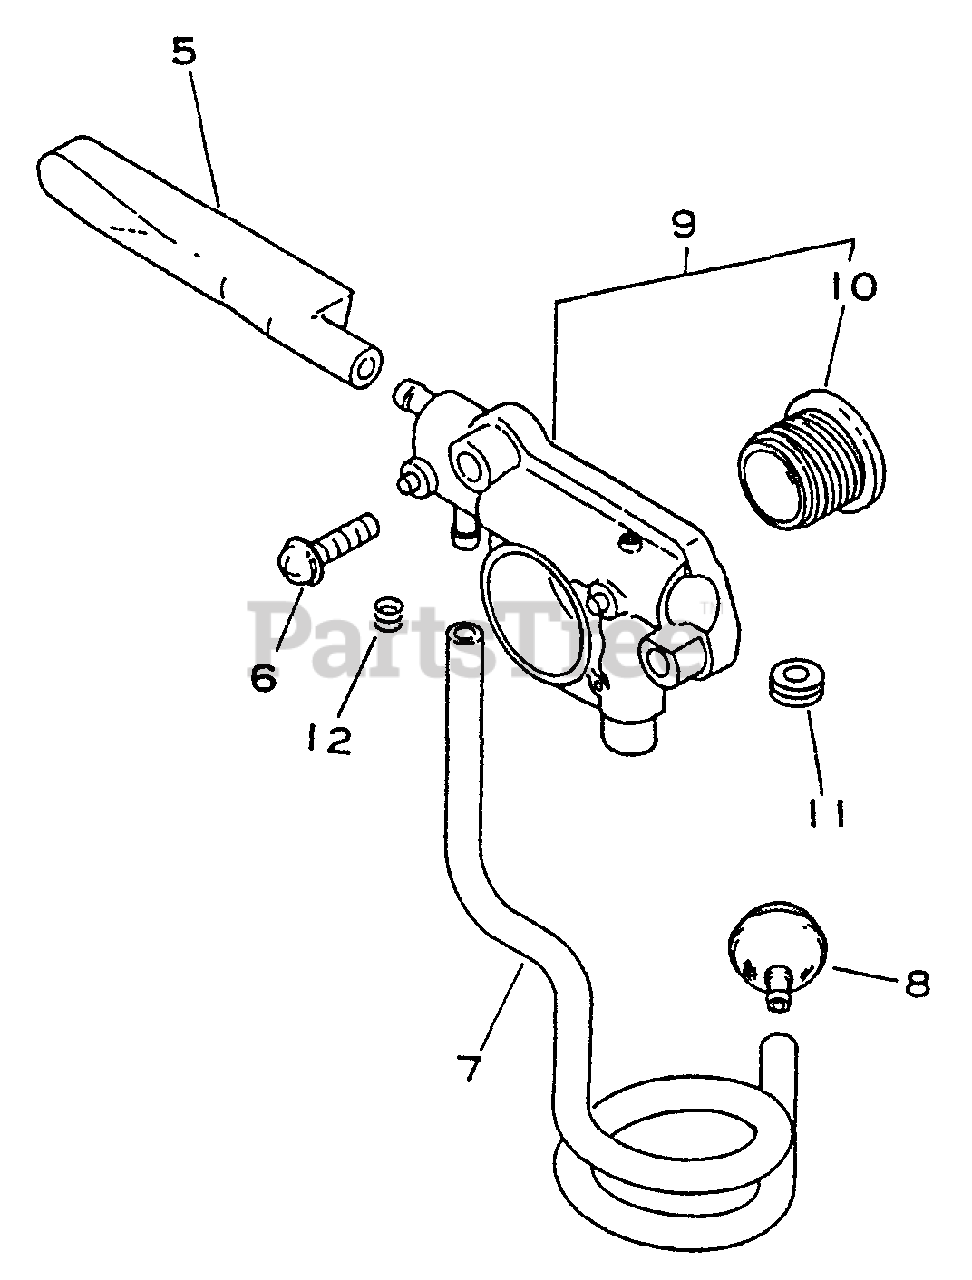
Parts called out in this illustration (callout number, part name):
5	PIPE - OIL
6	SCREW - 4X16
7	PIPE - OIL
8	FILTER, OIL
9	AUTO-OILER ASSY
10	GEAR - WORM
12	CLIP - 6.6
